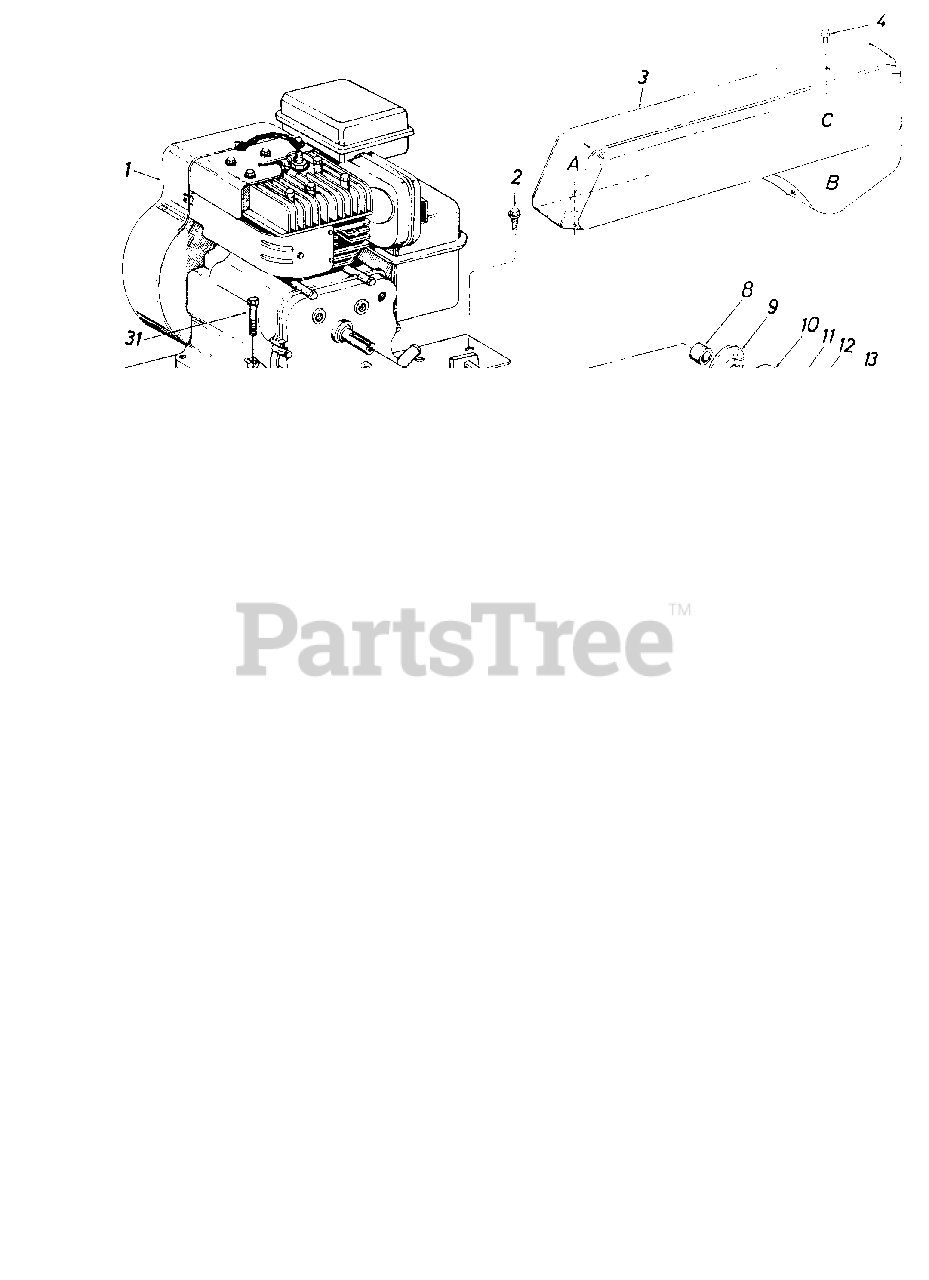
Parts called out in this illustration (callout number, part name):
1	Engine
2	Hex Wash. Hd. Self-Tap Scr. 5/16-24 x .50" Lg.
3	Belt Cover
4	Hex Wash. Hd. Self-Tap Scr. 1/4-20 x .50" Lg.
5	Belt Keeper Brkt. Ass'y.
6	Hex Bolt 5/16-24 x 2.25" Lg. (Gr. 5)
7	Hex Bolt 5/16-24 x .62" Lg. (Gr. 5)
8	Spacer
9	Pulley Half
10	Pulley Half
11	Fl-Wash. 3/8" I.D. x 1.25" O.D. x .100
12	L-Wash. 3/8" I.D.
13	Hex Scr. 3/8-24 x 1.00" Lg.
14	Hex Wash. Hd. Self-Tap Scr. 3/8-24 x 7/8" Lg.
15	Handle Mounting Brkt. Ass'y.
16	U-Channel Brkt. Ass'y.
17	Idler Mounting Brkt.
18	Shld. Bolt
19	Idler Brkt. Ass'y.
20	Hex Scr. 3/8-16 x 1.50" Lg.
21	Idler Pulley
22	L-Wash. 3/8" I.D.
23	Hex Nut 3/8-16 Thd.
25	L-Wash. 3/8" I.D.
26	Hex Nut 3/8-16 Thd.
27	Hex Wash. Hd. Self-Tap Scr. 1/4-20 x .50" Lg.
28	Belleville Wash. .26 I.D. x .75 O.D. x .060
29	Hex Scr. 5/16-18 x 3.0" Lg.
30	Hex Nut 5/16-18 Thd.
31	Hex Bolt 5/16-18 x 1.50" Lg.
35	Clevis Pin
36	L-Wash. 5/16" I.D.
37	Frame Rail L.H.
38	Front Brace Brkt.
39	Hex Scr. 5/16-18 x .75" Lg.
40	L-Wash. 5/16" I.D.
41	Hex Cent. L-Nut 5/16-18 Thd.
42	Frame Rail R.H.
43	Hex Cent. L-Nut 5/16-18 Thd.
44	L-Wash. 5/16" I.D.
45	Spacer
46	Tine Shield
